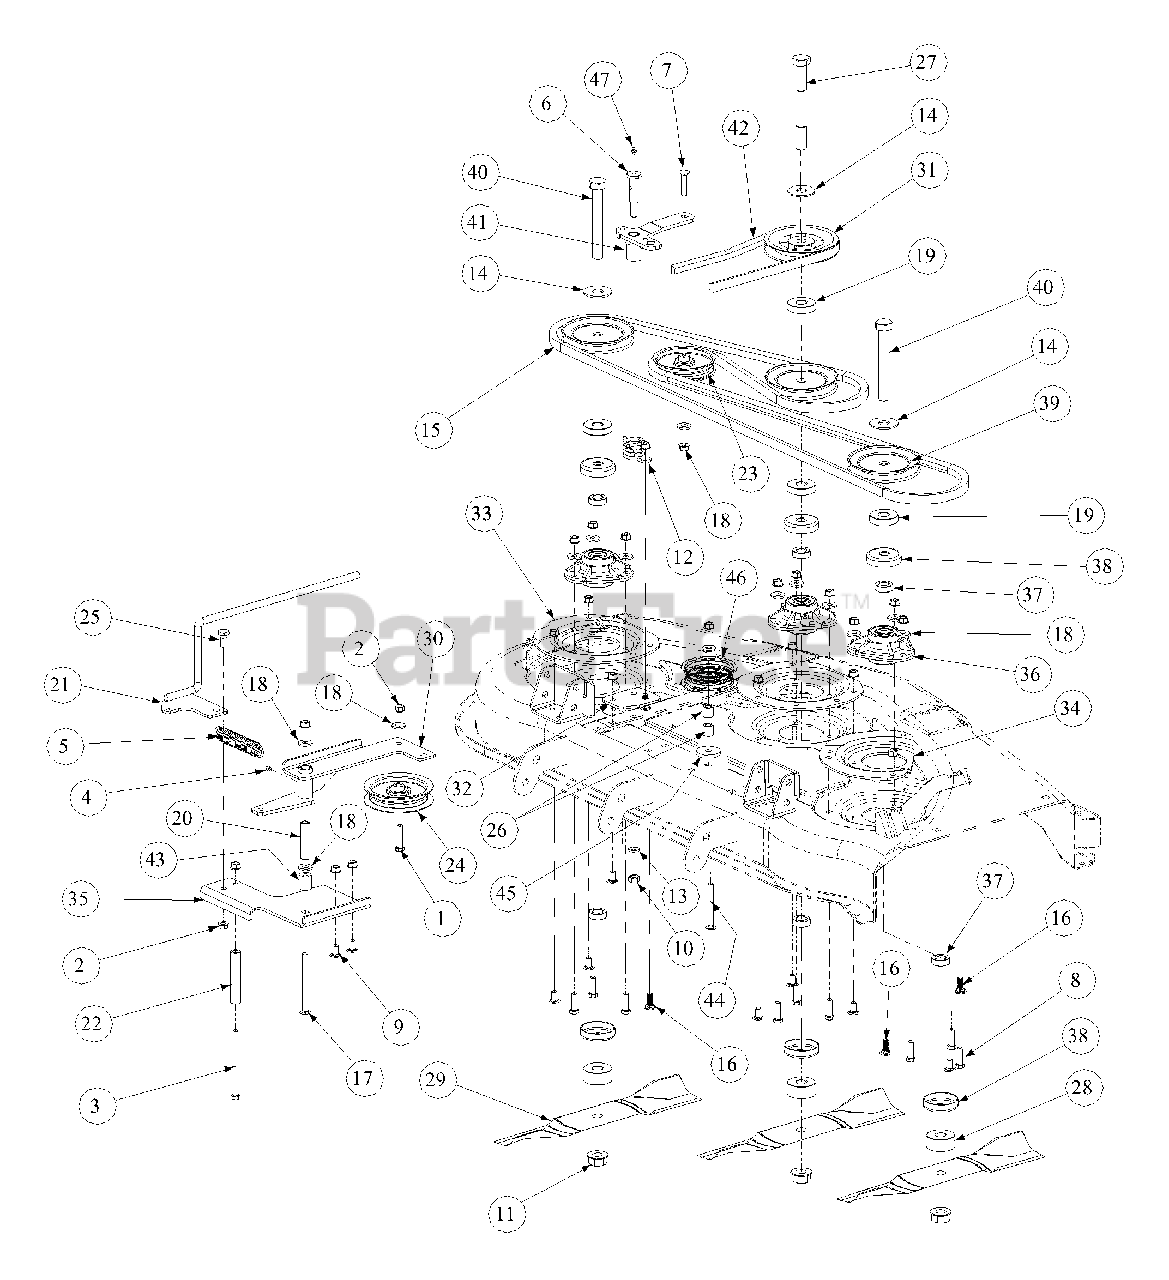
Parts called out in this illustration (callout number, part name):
1	Capscrew, 3/8-16 x 1-3/4
2	Hex Nut, 3/8-16, Flange Lock
3	Capscrew, 3/8-16 x 5.00
4	Grease Fitting, 1/4-28 x 3/16
5	Extension Spring, 1.0 OD x 5.00
6	Shoulder Screw, 7/16-14
7	Hex Carriage Screw, 3/8-16 x 1.75
8	Capscrew, 3/8-16 x 1.25
9	Carriage Bolt 3/8-16 x .75
10	Hex Nut, 7/16-14
11	Nut, 3/4-16, Hex Flange
12	Idler Spring
13	Lock Washer, 7/16
14	Flat Washer, .781 ID x 2.00 OD x .105
15	Belt, A Section x 107.3
16	Carriage Bolt, 3/8-16 x 1
17	Carriage Bolt, 3/8-16 x 5.0
18	Flat Washer, .406 ID x 1.0 OD x .105
19	Spacer, .76 ID x 2.00 OD x .477
20	Spacer, .39 ID x .625 OD x 2.75
21	Spring Tension Rod Assembly
22	Spacer, .405 x .75 x 3.875
23	Flat Pulley
24	Idler Pulley, 4.06 OD
25	Shoulder Screw, .50 x .27 Lg., 3/8-16
26	Spacer, .385 ID x .75 OD x .875
27	Capscrew, 3/4-16 x 6.50
28	Spacer, .760 ID x 2.00 OD x 0.9
29	Hi-Lift Blade, 16.5, 0.756 ID
30	Idler Arm Assembly, Flat Top Bearing
31	V-Pulley, 4.75 OD
32	Idler Arm Mounting Plate
33	Spindle Support Plate
34	RH Spindle Support PLate
35	Idler Arm Mounting Bracket
36	Housing Assembly
37	Spacer, .76 ID x 1.25 OD x .44
38	Spindle Spacer
39	V-Pulley, 4.9 OD
40	Capscrew, 3/4-16 x 5.50
41	Idler Arm Assembly, Deck Spindle
42	V-Belt, B-Section
43	Spacer, .39 ID x .63 OD x 1.442
44	Carriage Bolt, 3/8-16 x 3.5
45	Washer, 7/16 ID x 1.75 OD x .25
46	FLAT IDLER W/FLANGES 3.5 OD
47	Grease Fitting, 1/4-28, 90 degree
